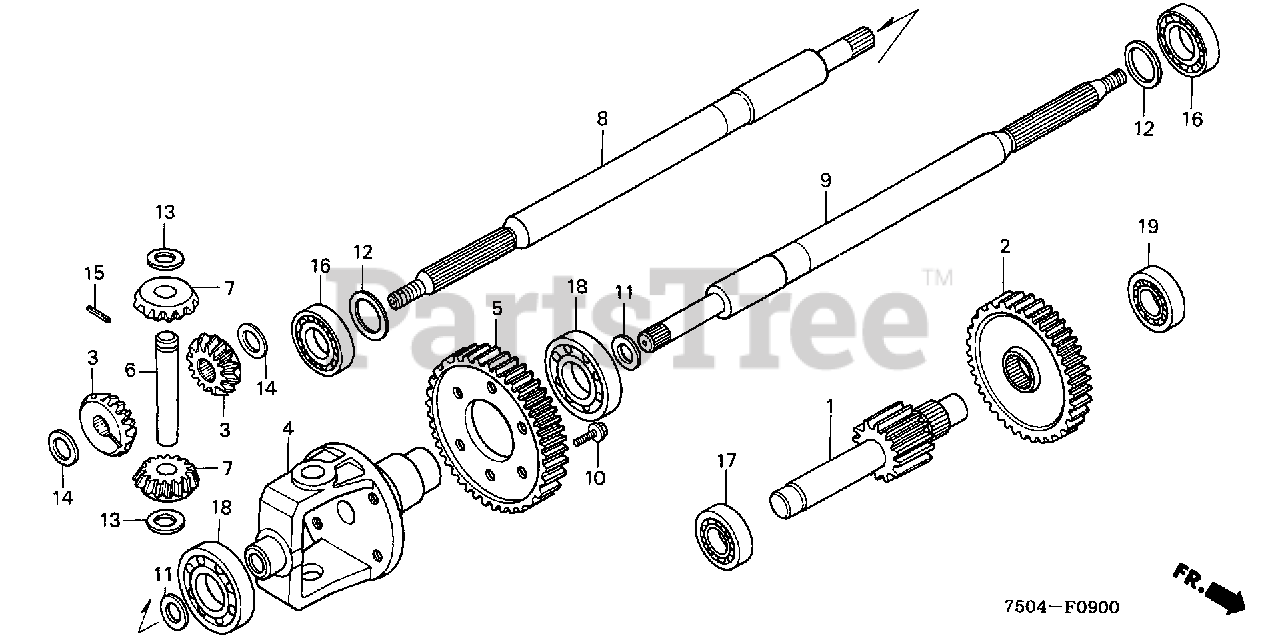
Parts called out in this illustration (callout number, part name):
1	COUNTERSHAFT
2	GEAR, COUNTERSHAFT DRIVEN (52T)
3	GEAR, DIFFERENTIAL (16T)
4	CASE, DIFFERENTIAL GEAR (NOT AVAILABLE)
5	GEAR, FINAL DRIVEN (49T)
6	SHAFT, DIFFERENTIAL PINION
7	PINION, DIFFERENTIAL (16T)
8	SHAFT, R. AXLE
8	SHAFT, R. AXLE (NOT AVAILABLE)
9	SHAFT, L. AXLE
9	SHAFT, R. AXLE
9	SHAFT, L. AXLE (NOT AVAILABLE)
10	BOLT, SPECIAL (10X20)
11	WASHER, RR. AXLE (20MM)
12	WASHER, RR. MIDDLE (NOT AVAILABLE)
13	WASHER A, DIFFERENTIAL PINION
13	WASHER B, DIFFERENTIAL PINION
13	WASHER C, DIFFERENTIAL PINION
13	WASHER D, DIFFERENTIAL PINION
14	WASHER, DIFFERENTIAL GEAR
15	PIN, SPRING (4X32)
16	BEARING, RADIAL BALL (6005)
17	BEARING, RADIAL BALL (6203)
18	BEARING, RADIAL BALL (6206)
19	BEARING, RADIAL BALL (6304)
